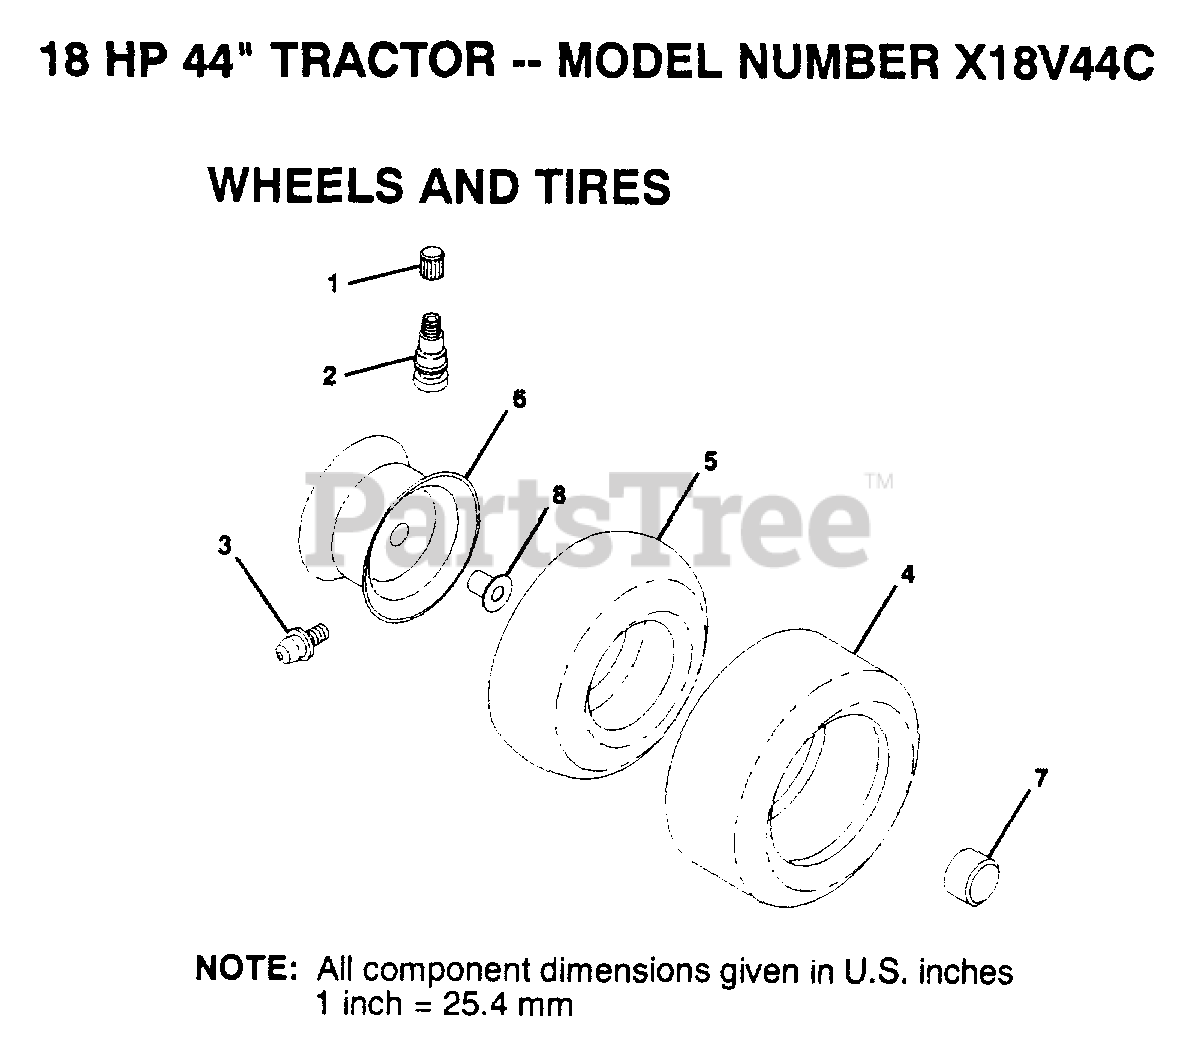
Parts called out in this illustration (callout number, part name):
1	VALVE CAP
2	VALVE STEM LT
3	FITTING LT
5	TUBE.5.3/4.5/6
5	TUBE.23X8/10-12
7	HUB CAP
8	"FLANGE, BEARING"
